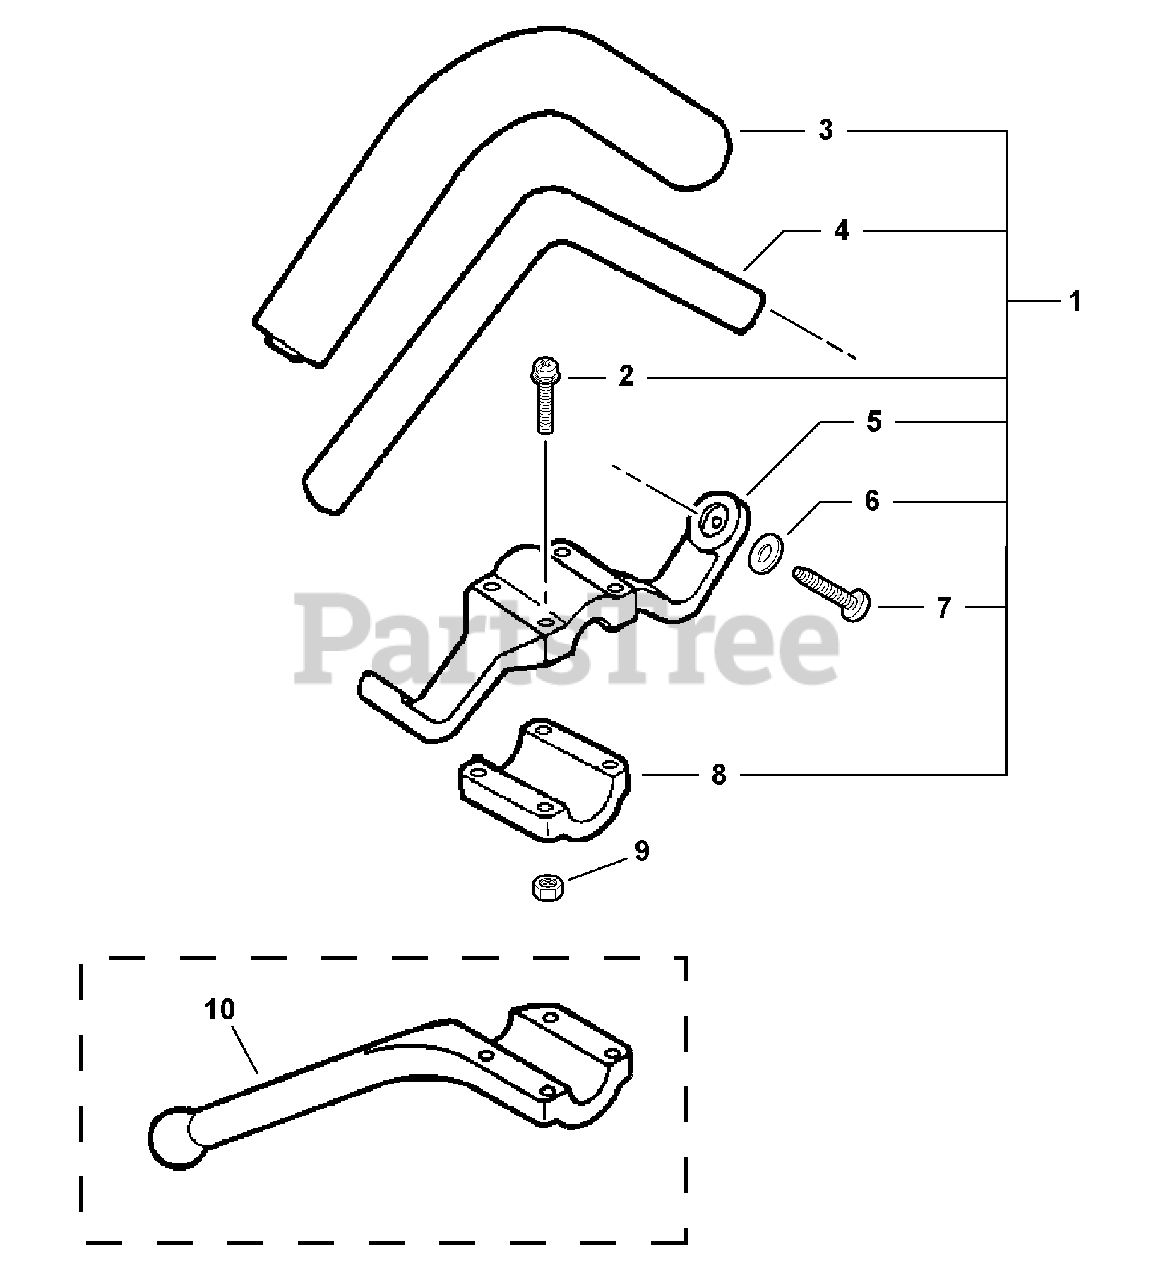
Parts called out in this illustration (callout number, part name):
1	Front Handle Asy
2	Screw 5x35
3	Grip, Handle
4	Handle, Front
5	Bracket, Handle - Upper
6	Washer 5
8	Bracket, Handle - Lower
10	Bar, Barrier
